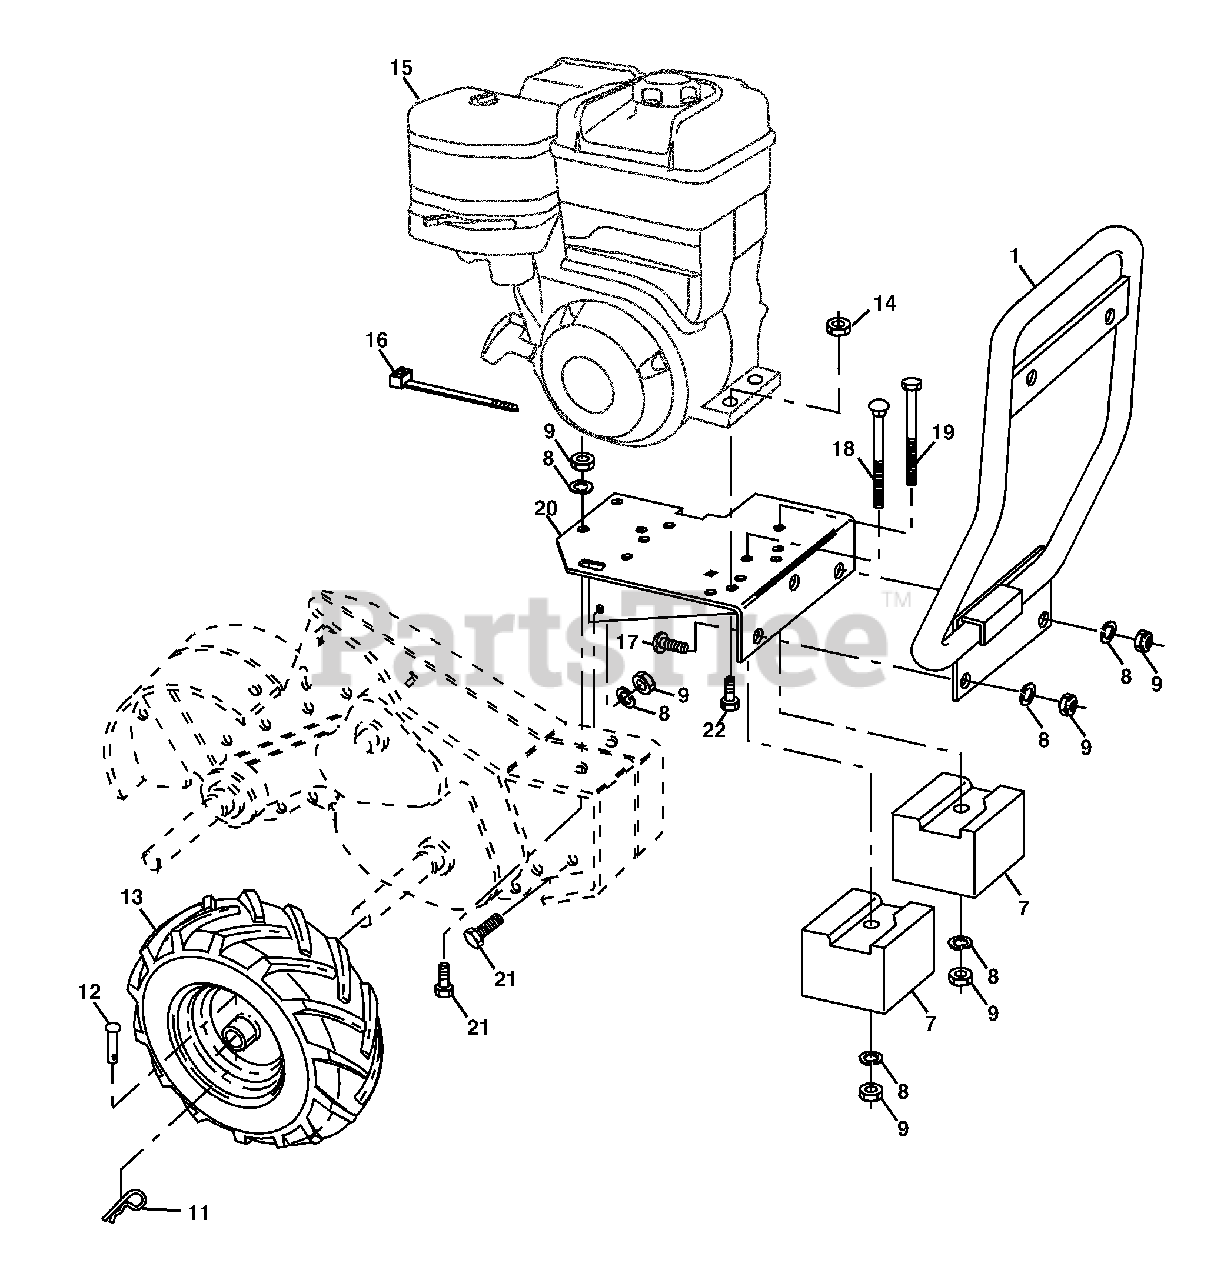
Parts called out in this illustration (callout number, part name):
7	Counter Weight, R.H.
8	Washer, Lock 3/8
9	Nut, Hex 3/8-16
11	Clip, Hairpin
12	Rivet, Drilled
13	Tire
13	Rim
13	Tire Valve
14	Nut, Lock Hex Flange
16	Tie Cable
17	Bolt, Hex 5/16-18 x 1-1/2
18	Bolt 3/8-16 x 4-1/2
19	Bolt Hex 3/8-16 x 4-1/2
20	Bracket, Reinforcement
21	Bolt, Hex 5/16-18 x 2
22	Bolt Hex Hd 5/16-18 x 1-1/2
